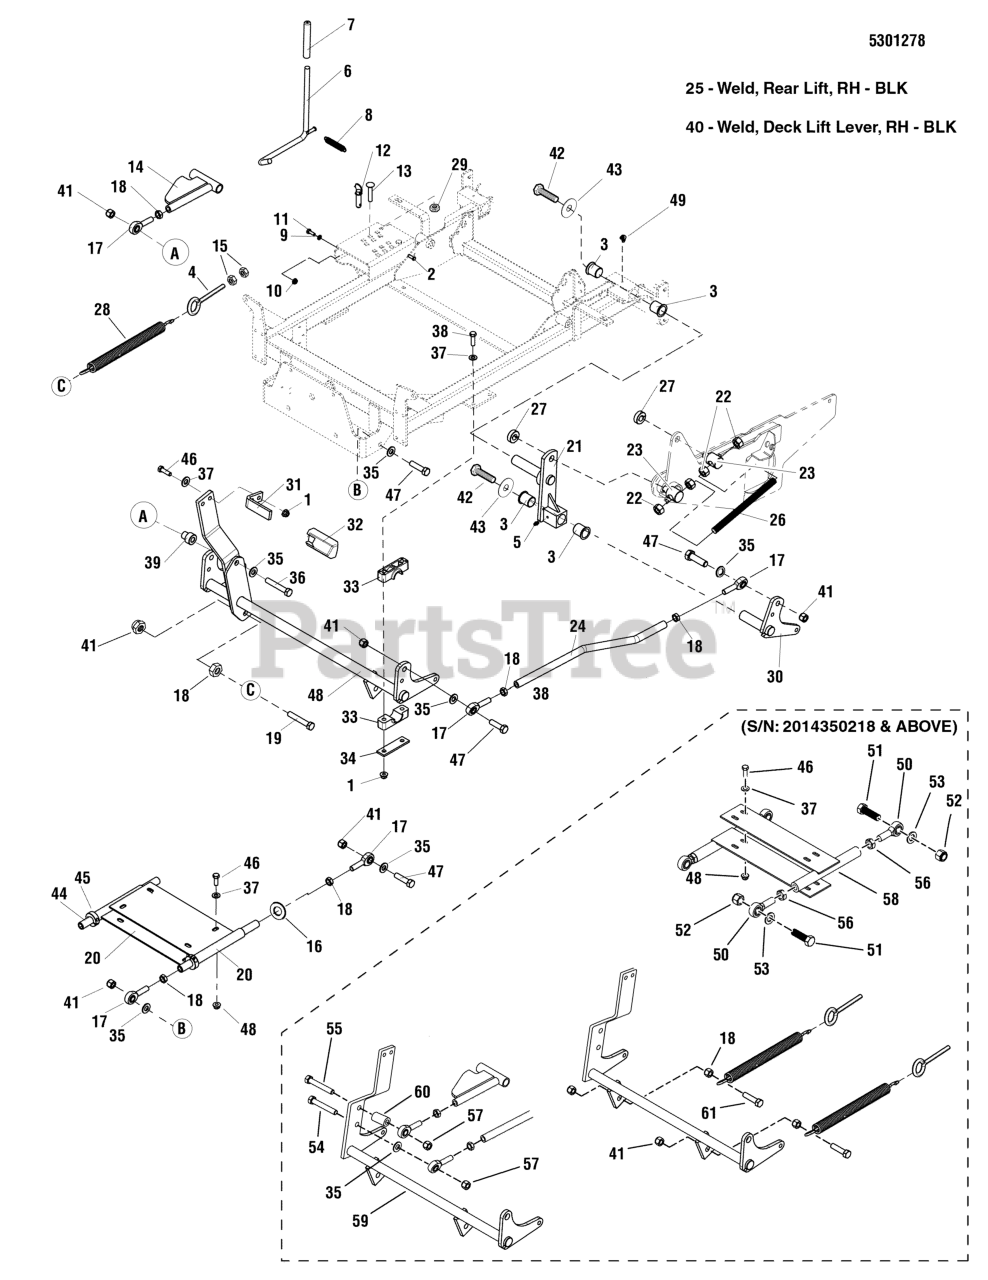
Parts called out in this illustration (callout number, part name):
1	NUT, 3/8-16 HEX NYLOCK FLANGE
2	CLEVIS PIN, 1/4 X 1/2, YZ
3	BUSHING, 1.00 X 1.13 X 1.38, PLASTIC
4	EYE BOLT, 3/8-16 X 4-1/4, 1 EYE
5	GREASE FITTING, 1/4-28 STRAIGHT
6	WELD, ROD DECK LIFT - BLK
7	GRIP, FOAM
8	SPRING, EXTENSION
9	WASHER, 1/4 SAE
10	NUT, 1/4-20 HEX SERR. FLANGE
11	BOLT, 1/4-20 X 3/4 GD5 YZ
12	PIN, HITCH, 1/2 X 2.00 OAL, YP
13	BOLT, 3/8-16 X 2, CARRIAGE
14	WELD, DECK ADJUST LINK - RED
15	NUT, 3/8-16 HEX
16	WASHER, 1/2 SAE
17	BALL JOINT, 1/2-20, MALE
18	NUT, 1/2-20 HEX JAM
19	BOLT, 1/2-13 X 2-1/4" GD5 CZ
20	WELD, DECK STABILIZER - BLK
21	WELD, REAR LIFT, LH - BLK
22	NUT, 5/8-11 HEX
23	PIVOT, SPRING ROD
24	ROD, DECK LIFT BENT
26	ROD, 5/8-11 X 9.00
27	COLLAR, 5/8 SPLIT
28	SPRING, DECK LIFT ASSIST
29	NUT, 3/8-16 HEX SIDE LOCK
30	WELD, DECK LIFT LEVER, LH - BLK
31	PEDAL, FOOT - BLK
32	PEDAL, Rubber
33	PIVOT BLOCK, PLASTIC
34	PLATE, PIVOT BLOCK SUPPORT - BLK
35	WASHER, 1/2 GD9 YZ
36	BOLT, 1/2-13 X 3-1/2, HEX HD, GD5, CZ (SV)
37	WASHER, 3/8 SAE
38	BOLT, 3/8-16 X 2-3/4" GD5 CZ
39	ADAPTER, CASTER AXLE, CZ
41	NUT, Hex, Nylon Lock, 1/2-20
42	BOLT, 3/8-16 X 3/4, PLT W/PATCH
43	WASHER, .390 X 1.50 X .109, YZ
44	SHAFT, DECK STABILIZER
45	COLLAR, 3/4 SPLIT
46	BOLT, 3/8-16 X 1" GD5 CZ
47	BOLT, 1/2-20 X 1-3/4" GD8 CZ
48	WELD, DECK LIFT SHAFT - RED
49	GREASE FITTING, 1/4-28, 90 DEGREE
50	BALL JOINT, 3/4-16, MALE
51	BOLT, 3/4-16 X 2-1/2 YZ GD5
52	NUT, 3/4-16 HEX NYLON LOCK
53	WASHER, 3/4 SAE
54	BOLT, 1/2-13 X 3-1/2, HEX HD, GD5, CZ (SV)
55	BOLT, 1/2-13 X 4" GD5 CZ
56	NUT, 3/4-16 HEX JAM
57	NUT, 1/2-13 HEX SIDE LOCK
58	WELD, DECK STABILIZER, IS1500ZX - BLK
59	WELD, DECK LIFT SHAFT - RED
60	SPACER, .52 X 1.00 X 1.75
61	BOLT, 1/2-13 X 2" GD5 CZ
